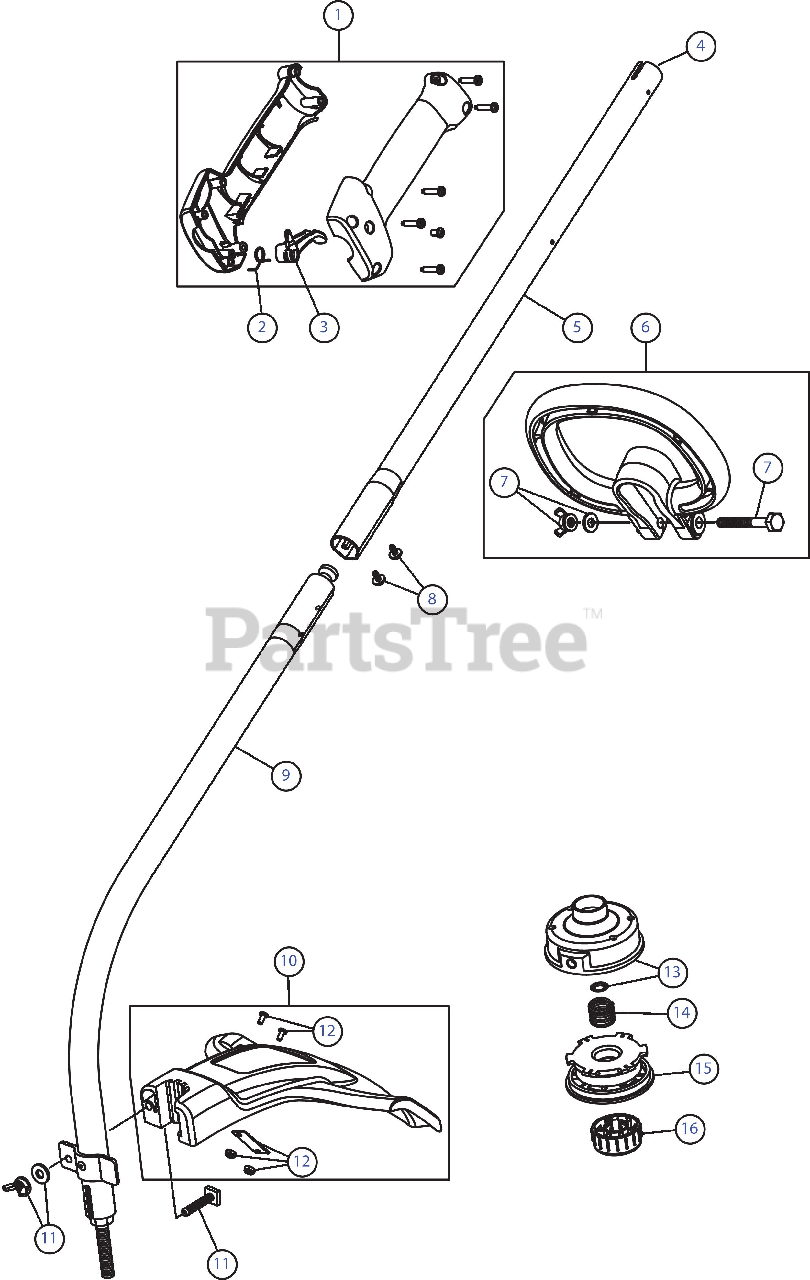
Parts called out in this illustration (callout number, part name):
1	Throttle Housing Assembly (includes 2 & 3)
2	Throttle Trigger Spring
3	Throttle Trigger
4	Flexible Drive Shaft
5	Upper Shaft Housing Assembly
6	D-Handle (includes 7)
7	D-Handle Hardware
9	Lower Shaft Housing Assembly
10	Shield Assembly (includes 11 & 12)
11	Shield Mounting Hardware
12	Blade Assembly
13	Outer Spool Assembly (with Retainer)
15	Inner Reel
16	Bump Head Knob Assembly
